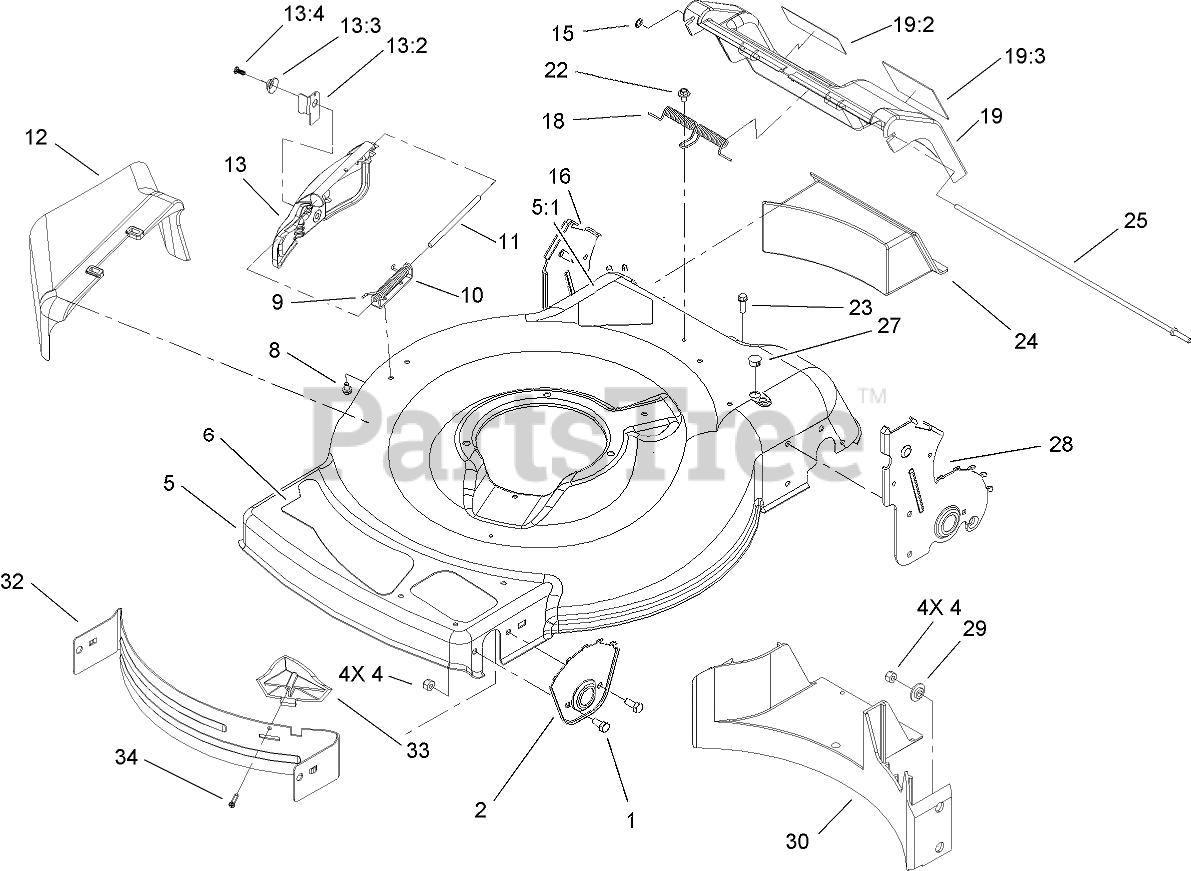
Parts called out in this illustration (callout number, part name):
1	SCREW-HH
2	Plate-HOC, Front
4	NUT-LOCK, NI
5	HOUSING
5:1	DECAL-DANGER
6	DECAL-RECYCLER (RWD)
8	SCREW-HWH
9	SPRING-TORSION
10	BRACKET-COVER
11	ROD-COVER
12	CHUTE-DISCHARGE, SIDE
13	DISCHARGE DOOR ASM
13:2	LATCH-DOOR
13:3	CAP-DOOR
13:4	SCREW-PLASTITE
15	NUT-PUSH
16	8 INCH RH HOC PLATE ASM
18	Spring-Door, Rear
19	REAR DOOR ASM
19:2	DECAL-WARNING
19:3	DECAL-WARNING
22	SCREW AND WASHER ASM
23	SCREW-HWH
24	Plug-Discharge, Rear
25	Rod-Pivot, Rear Door
27	Plug-Dome
28	8 INCH LH HOC PLATE ASM
29	Washer-Stepped
30	Baffle-Rear
32	BAFFLE-FRONT
33	KICKER-FRONT
34	SCREW-PPH
